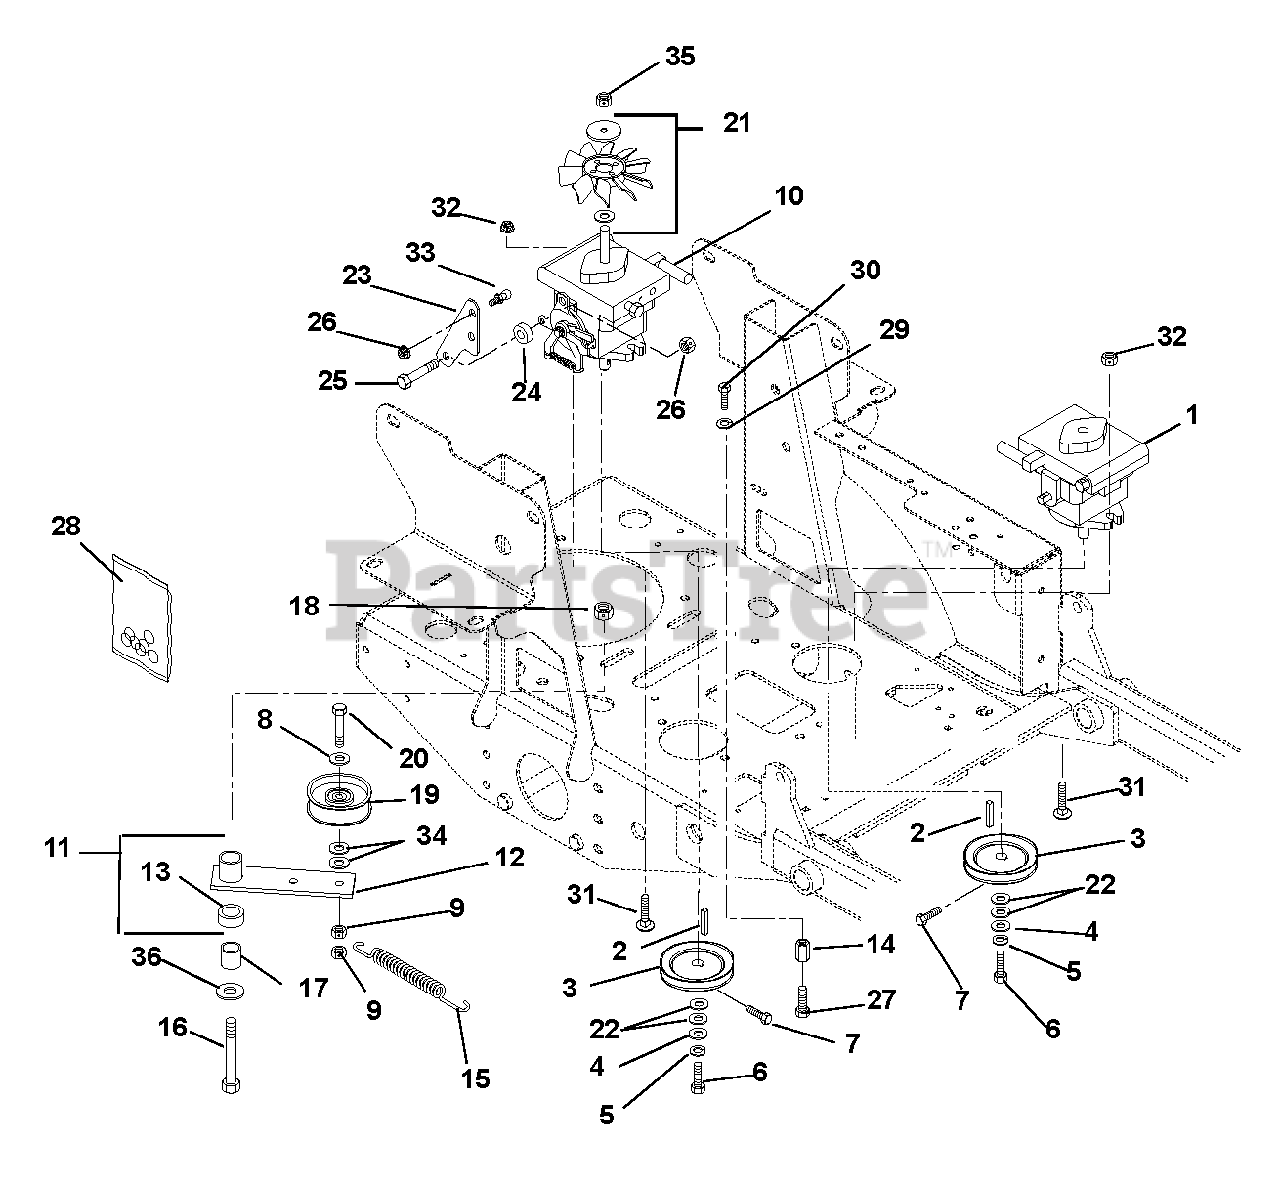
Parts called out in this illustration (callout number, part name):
1	Pump, Hydraulic BDP-10A Left Hand (page 16)
2	Key, Straight 5mm x 25mm x 5mm
3	Sheave 4.0 x .199
4	Washer, Flat Steel .281 x 1.00 x .063
5	Washer, Locking .25 x .062
6	Bolt, Hex M6 x 1.00 x 12 Epoxy 30
7	Bolt, Hex .25-20 x .50 Grade 5
8	Washer, Flat Steel .406 x .812 x .065
9	Nut, Nyloc Flange .38-16
10	Pump, Hydraulic BDP-10A Right Hand (page 17)
11	Assembly, Idler Arm Guard Drive (Includes 12 & 13)
12	Weldment, Idler Arm Ground Drive
13	Bearing, 1.00 x 1.12 x .75
14	Nut, Coupling .375-16 x 1.75
15	Spring, Extension
16	Bolt, Hex .50-13 x 3.50 Grade 5
17	Bushing, Spacer .505/.500 x .999/.996 x 2.05/2.03
18	Nut, Nyloc Flange .50-13
19	Idler, Flat 4.00 x .38 I.D.
20	Bolt, Hex .38-16 x 2.50 Grade 5
21	Fan, Cooling
22	Washer, Flat Steel .656 x 1.31 x .095
23	Bracket, Return to Neutral/Damper
24	Spacer .344 x 1.00 x .375
25	Bolt, Hex .31-18 x 1.25 Grade 5
26	Nut, Nyloc Flange .312-18
27	Bolt, Hex .38-16 x 1.50 Grade 5
28	Kit, Pump Seal (BDP-10A) (One kit required for each pump)
29	Washer, Locking .38 x .094
30	Bolt, Hex .38-16 x .75 Grade 5
31	Bolt, Round Head Square Neck .44-14 x 1.50 Grade 5
32	Nut, Nyloc Flange .44-14
33	Stud, Ball
34	Washer, Flat Steel .406 x 1.00 x .188
35	Nut, Center Lock .31-24
36	Washer, Flat Steel .511 x 1.441 x .125
